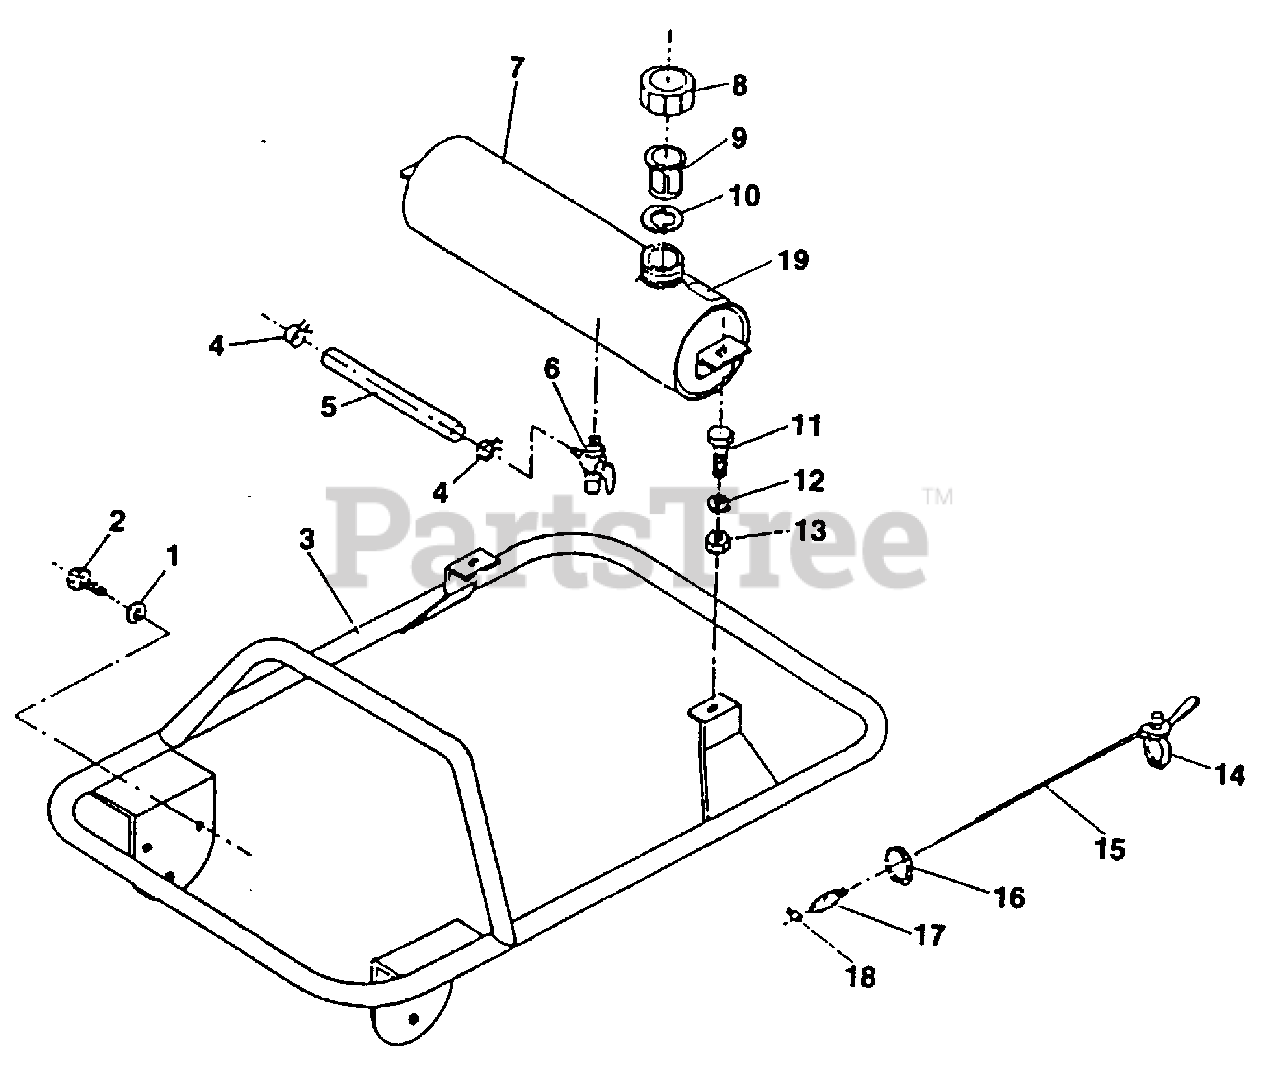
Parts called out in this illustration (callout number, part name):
1	WASHER- Spring m1O
2	BOLT- Hex m10 x 20
4	CLAMP- Hose
5	HOSE- Rubber
6	VALVE- Fuel
7	TANK- Fuel
8	CAP- Fuel
9	FILTER- Fuel Tank
10	GASKET- Fuel Tank
11	BOLT- Hex m8 x 20
12	WASHER- Spring m8
13	NUT- Hex m8
14	LEVER- Throttle
15	WIRE- Throttle
16	BAND- Wire
17	SPRING- Return
18	END- Screw
19	CAUTION DECAL
